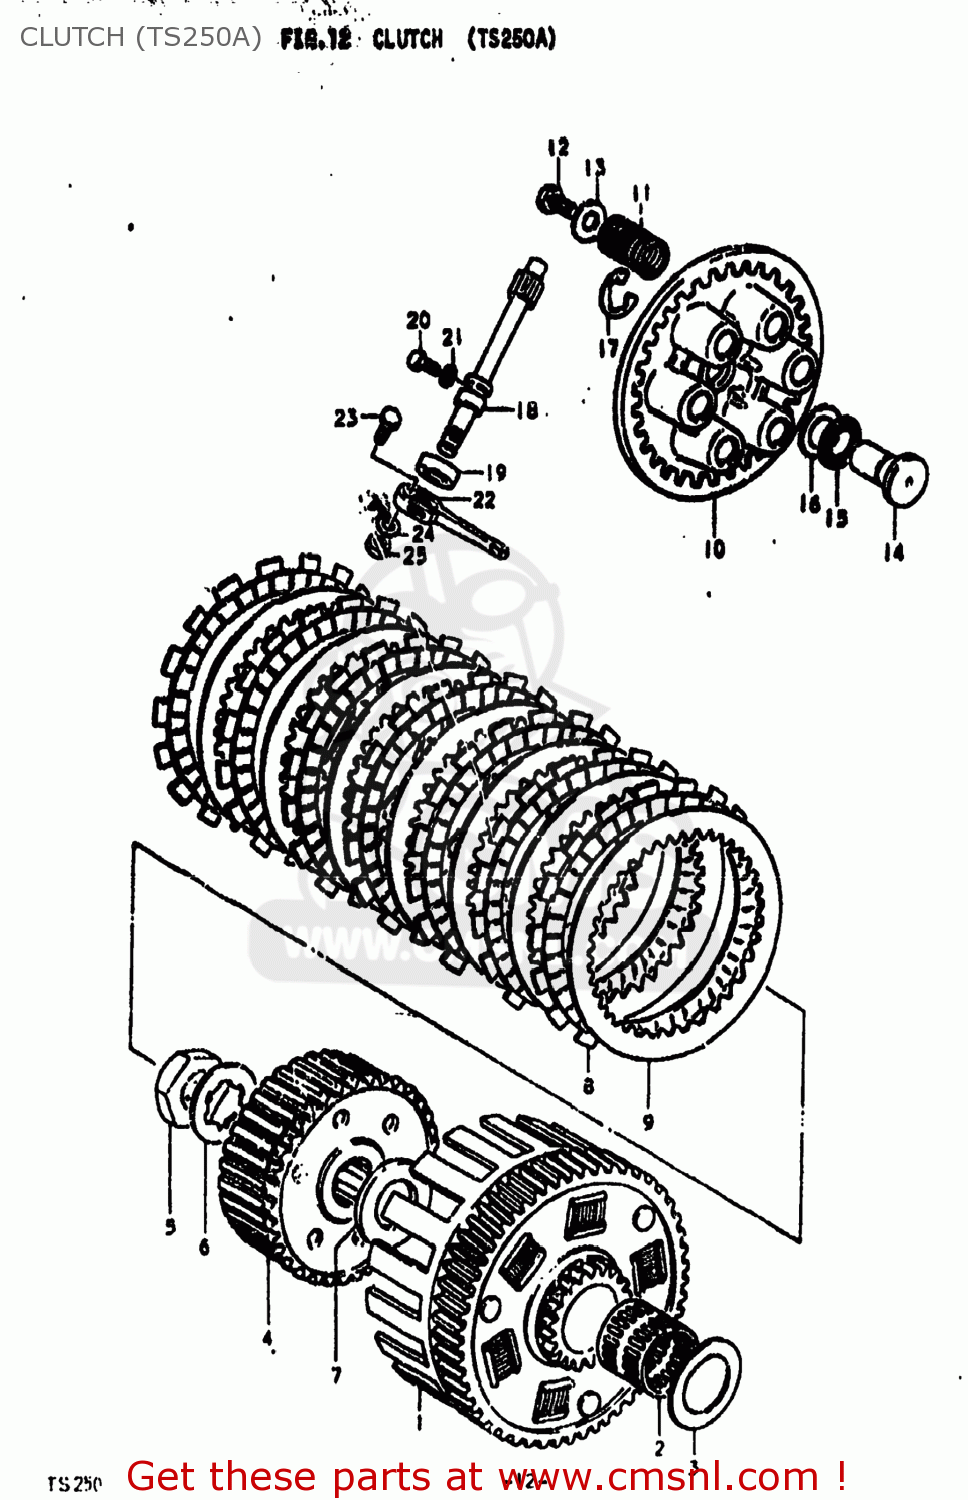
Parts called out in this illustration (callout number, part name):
1	GEAR ASSEMBLY,PRIMARY DRIVE
2	ROLLER BEARING (25X30X3
3	WASHER(25X41X3)
4	HUB,CLUTCH SLEEVE
5	NUT (20MM)
6	WASHER,LOCK
7	WASHER(20X44X3)
8	PLATE,CLUTCH DRIVE (MCA)
9	PLATE,CLUTCH DRIVEN(T:2.0) (NAS)
10	DISC,CLUTCH PRESSURE
11	SPRING
12	BOLT
13	WASHER
14	RACK,CLUTCH RELEASE
15	BEARING(15X28X2)
16	WASHER
17	E.RING
18	PINION,CLUTCH RELEASE
19	OIL SEAL
20	BOLT(6X12)
21	WASHER
22	ARM,CLUTCH RELEASE
23	BOLT
24	WASHER
25	NUT
